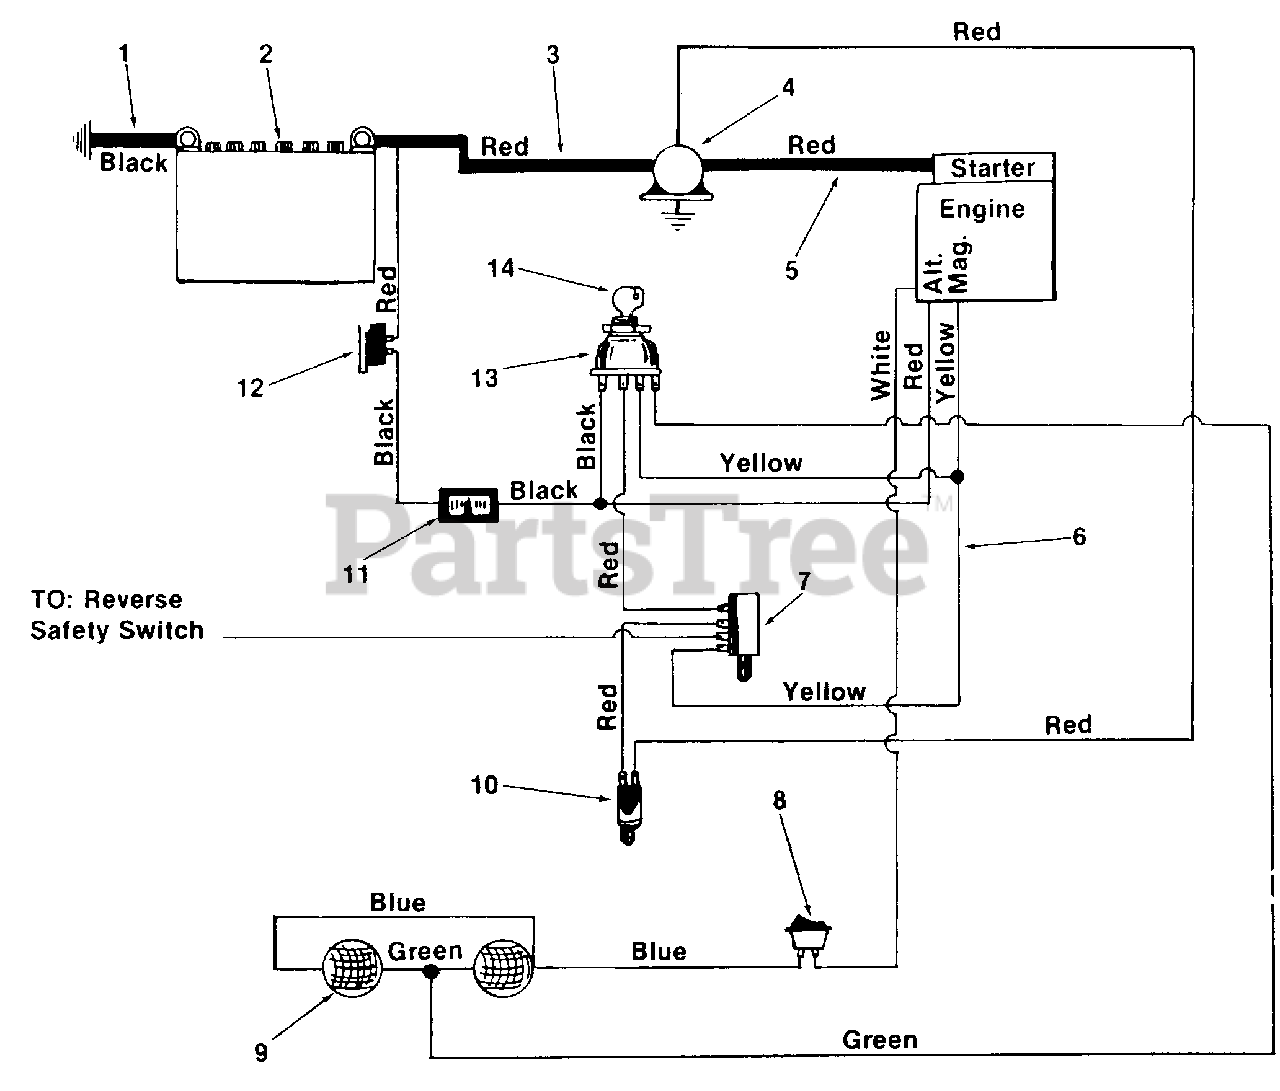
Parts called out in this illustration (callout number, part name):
1	Electric Ground Wire
2	12V-Battery
3	Electric Wire (Red Positive)
4	Solenoid
5	Electric Wire
6	Wire Harness
7	Safety Switch
8	Light Switch
9	Head Lights
10	Safety Switch
11	Ammeter
12	Circuit Breaker
13	Ignition Switch
14	Ignition Key
